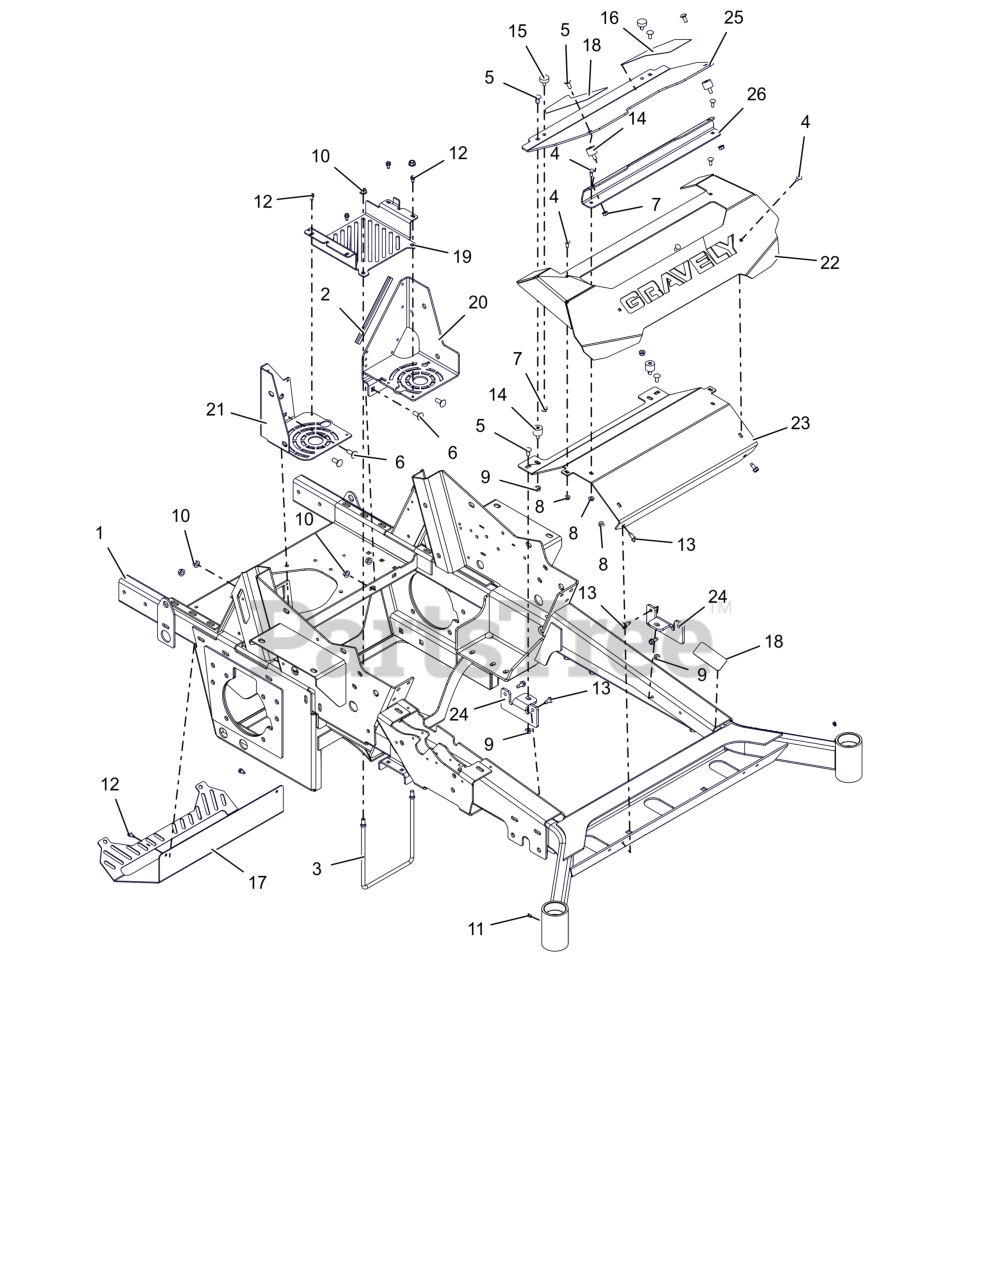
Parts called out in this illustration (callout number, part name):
1	WLDMT, MACH ONE, 72" FRAME (RED)
2	STRIP, COWL
3	ROD, BRAKE MTG
4	BLT, RHSN .25-20X.750 G5 ZCC
5	BLT, RHSSN.31-18X.750 G5 ZCC
6	BLT, RHSN .38-16X1.00 G5 ZCC
7	NUT,SPNLK-FLG .31-18 G5 ZCC
8	NUT-LK-CTR-FLG .25-20 ZC120
9	NUT,LK-CTR-FLG .31-18 GF ZCC
10	NUT-LK-CTR-FLG .375-16 GF ZCC
11	FTG, .25-28 FLUSH MNT GREASE
12	SCR-TAP .25-20X.50 HWH ZCC
13	SCR,TAP .312-18X.75 HWH TR ZCC
14	BUMPER,STUD MNTD W/FEMALE INSR
15	BUMPER, RUBBER
16	KIT, PT300-600 ANTI-SKID Tape
17	GUARD, MUFFLER (BLACK)
18	KIT, PT300-600 ANTI-SKID Tape
19	TRAY- BATTERY
20	GUSSET-LH BATTERY TRY/ROPS-RED
21	GUSSET- FAN GUARD/ROPS - RED
22	BMPR-PT300-500 FRT FTRST/ -RED
23	BRKT-FRT BUMPER MTG/BACKER-BLK
24	BRKT- FOOTREST MTG
25	FOOTREST, PT300-500 (RED)
26	BRKT, FOOTREST SUPPORT (BLK)
